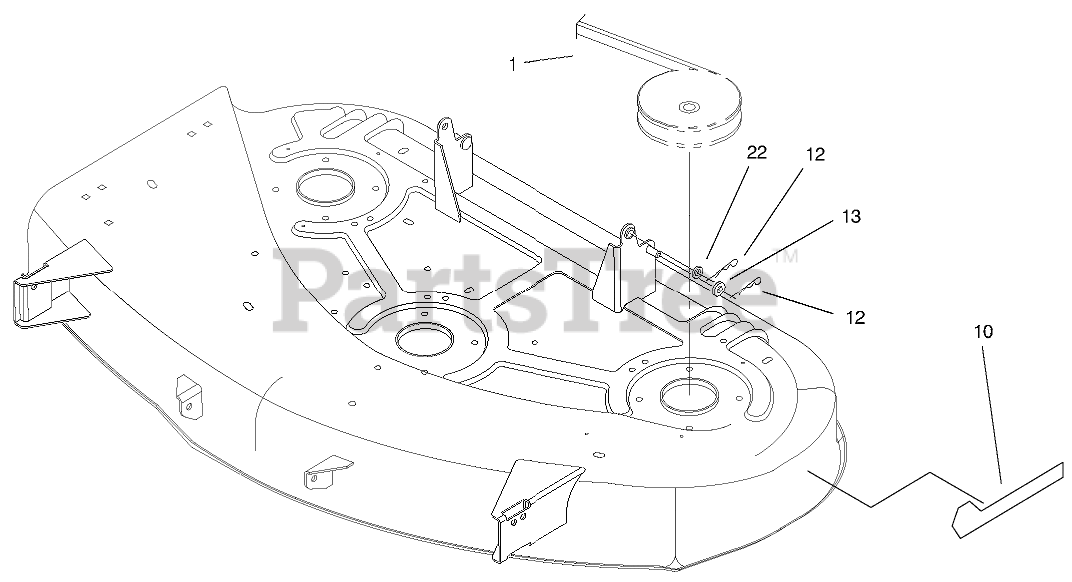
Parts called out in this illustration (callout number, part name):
1	V BELT-DECK
10	DECAL - RECYCLER DECK
12	PIN-COTTER
13	WASHER-HARDENED
22	WASHER-FLAT
